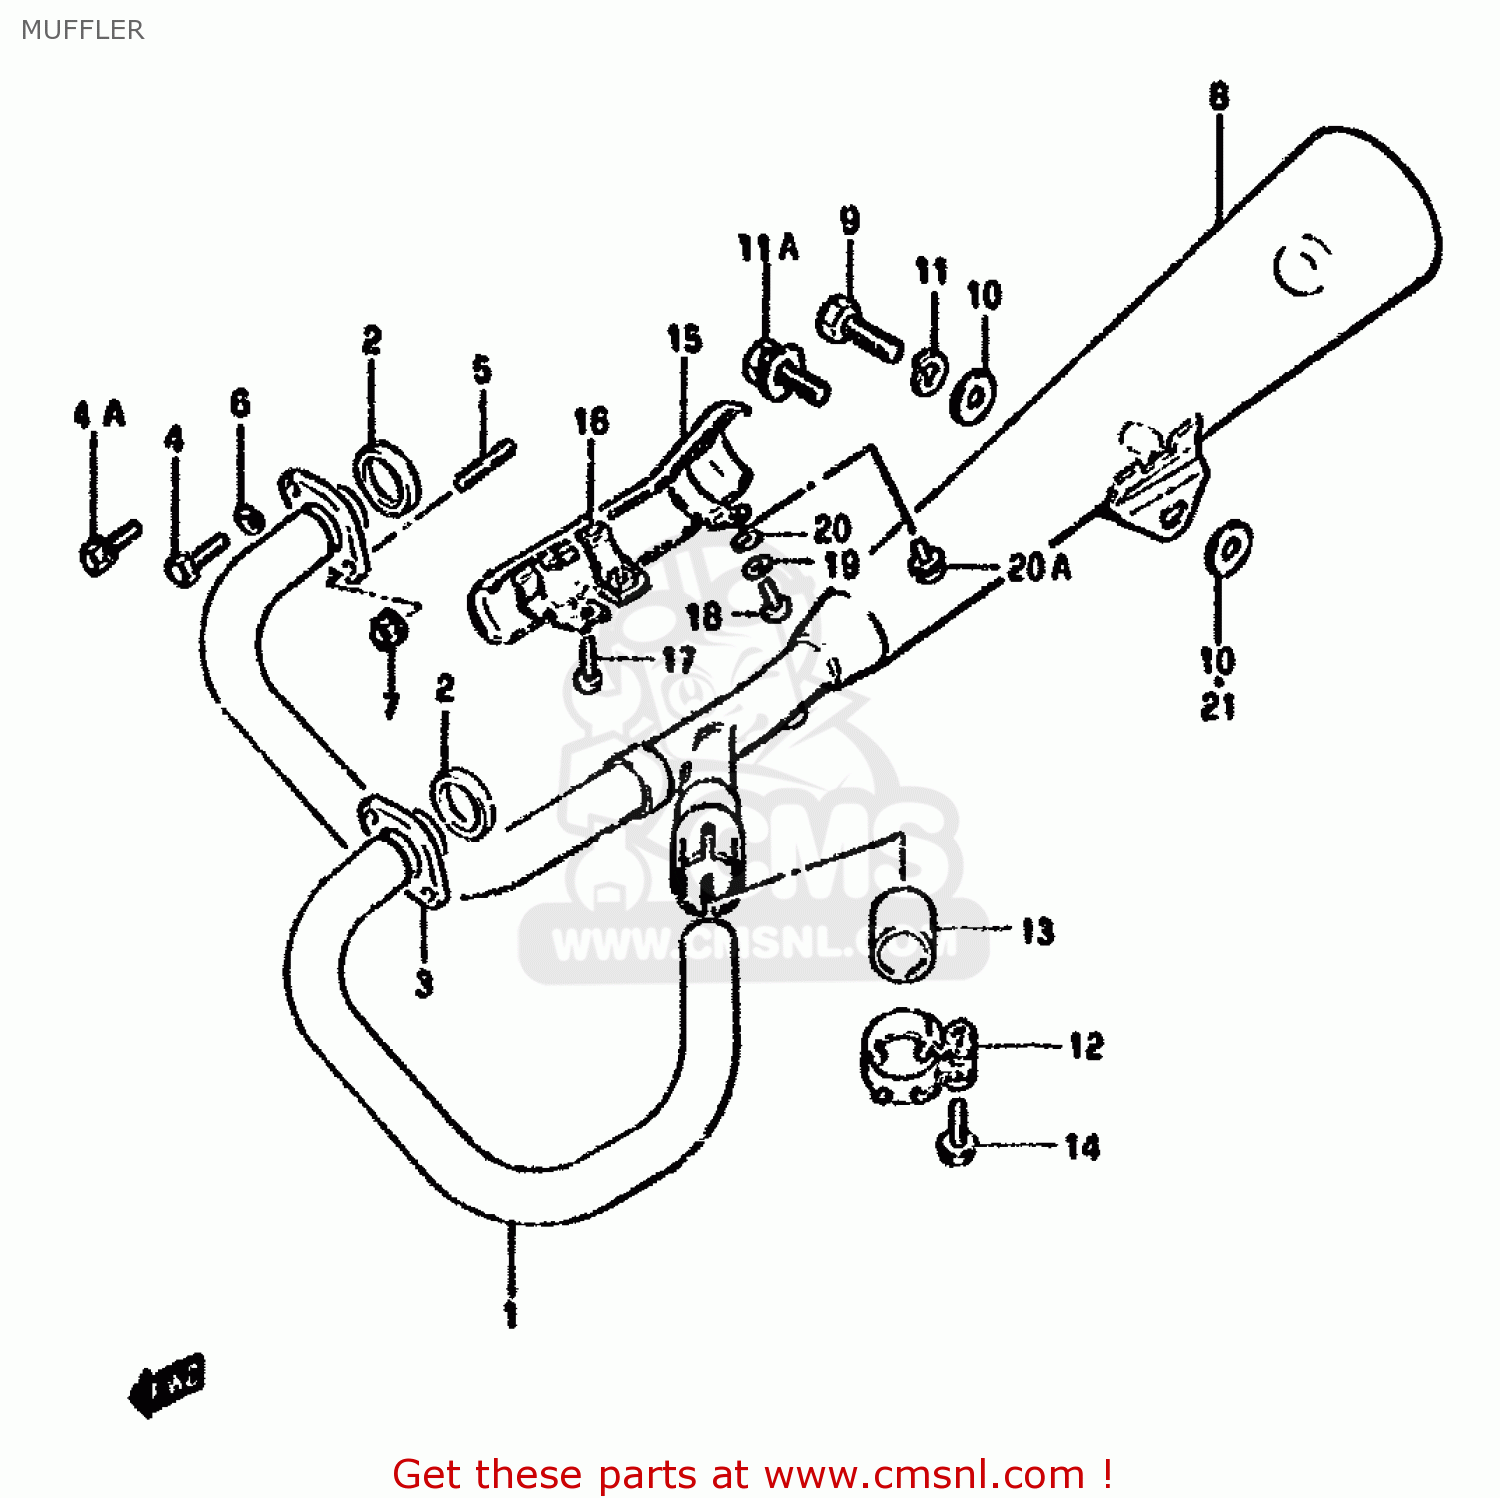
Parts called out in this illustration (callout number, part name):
1	PIPE,EXHAUST,L
2	GASKET,EXHAUST PIPE (NAS)
3	CLAMP
4	BOLT
4A	BOLT
5	STUD 6X20
6	WASHER,LOCK
7	NUT
8	MUFFLER ASSY
9	BOLT 10X25
10	WASHER
11	WASHER,LOCK,10
11A	BOLT
12	CLAMP
13	CONNECTOR,MUFFLER
14	BOLT
15	COVER,MUFFLER
16	CLAMP,MUFFLER COVER
17	SCREW
18	SCREW
19	WASHER,LOCK
20	WASHER
20A	SCREW
21	WASHER
